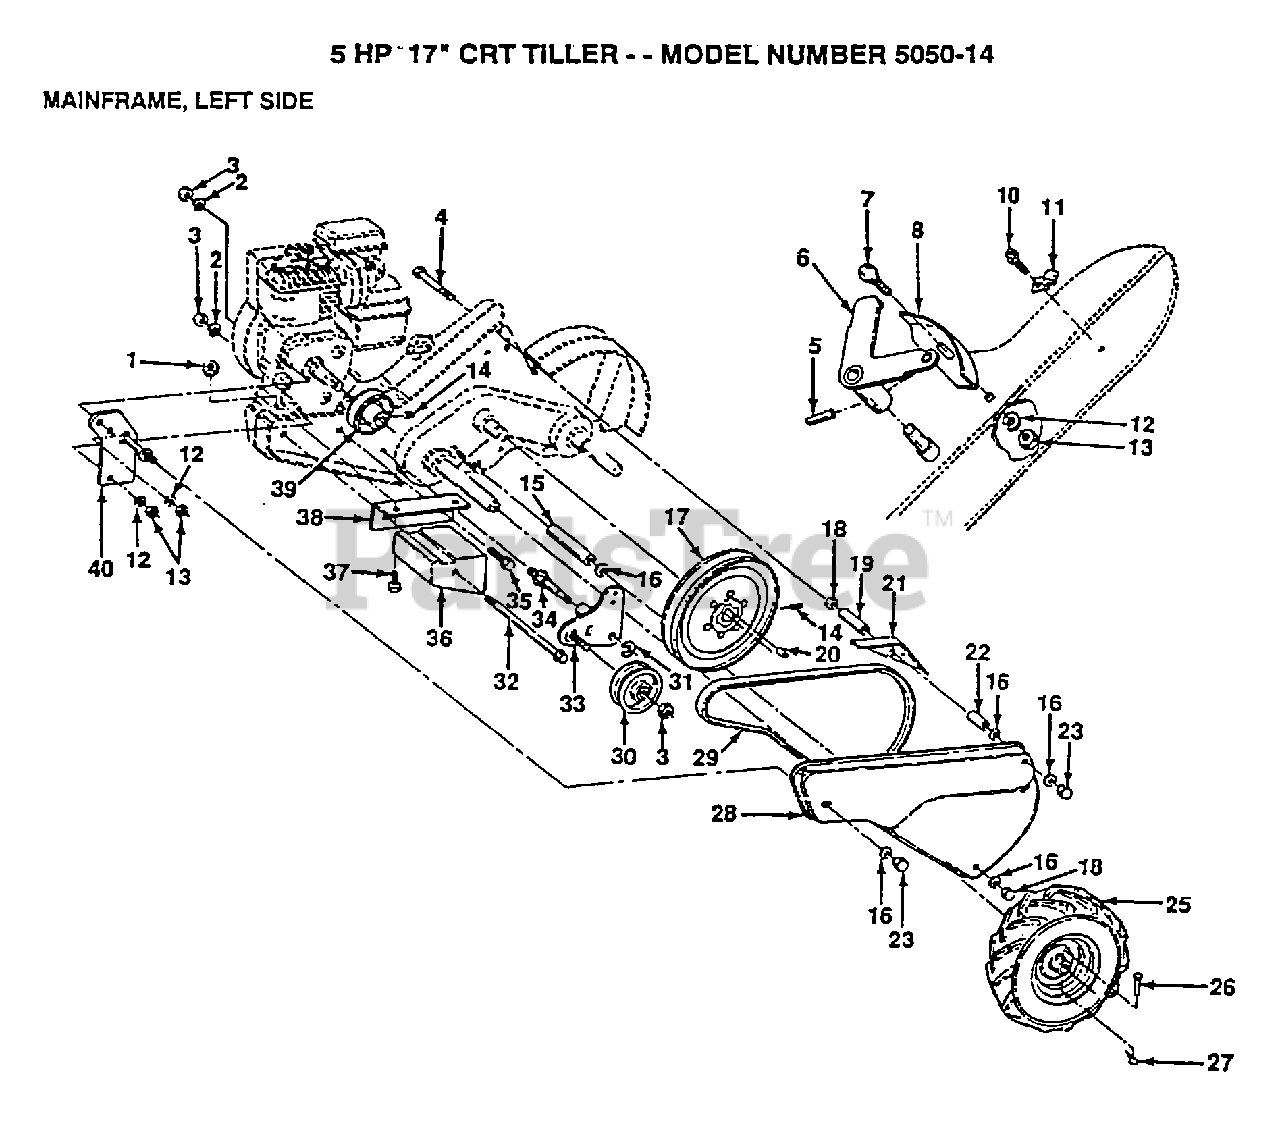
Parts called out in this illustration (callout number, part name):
1	LOCKNUT TI
2	LOCKWASHER
3	NUT.HEX.3/8-16UNC
4	BOLT-HEX TI
6	LEVER ASM CRT
7	BOLT
8	PANEL TI
11	CONDIUT CLIP T
12	LOCKWASHER
14	SET SCREW
15	SPACER
16	WASHER
17	"SHEAVE 10"" CRT"
18	NUT.HEX.5/16-18
19	SPACER CRT
20	KEY T
21	GUARD CRT
22	SPACER CRT
23	NUT TI
25	TIRE TI
26	RIVET.DRILL.1.75
27	RETAINER M
30	PULLEY-IDLER TI
31	KLIP RING
32	BOLT CRT
34	SHIFT ARM CRT
35	BOLT
36	COUNTERWEIGHT CRT
37	BOLT
38	BRACKET LH CRT
